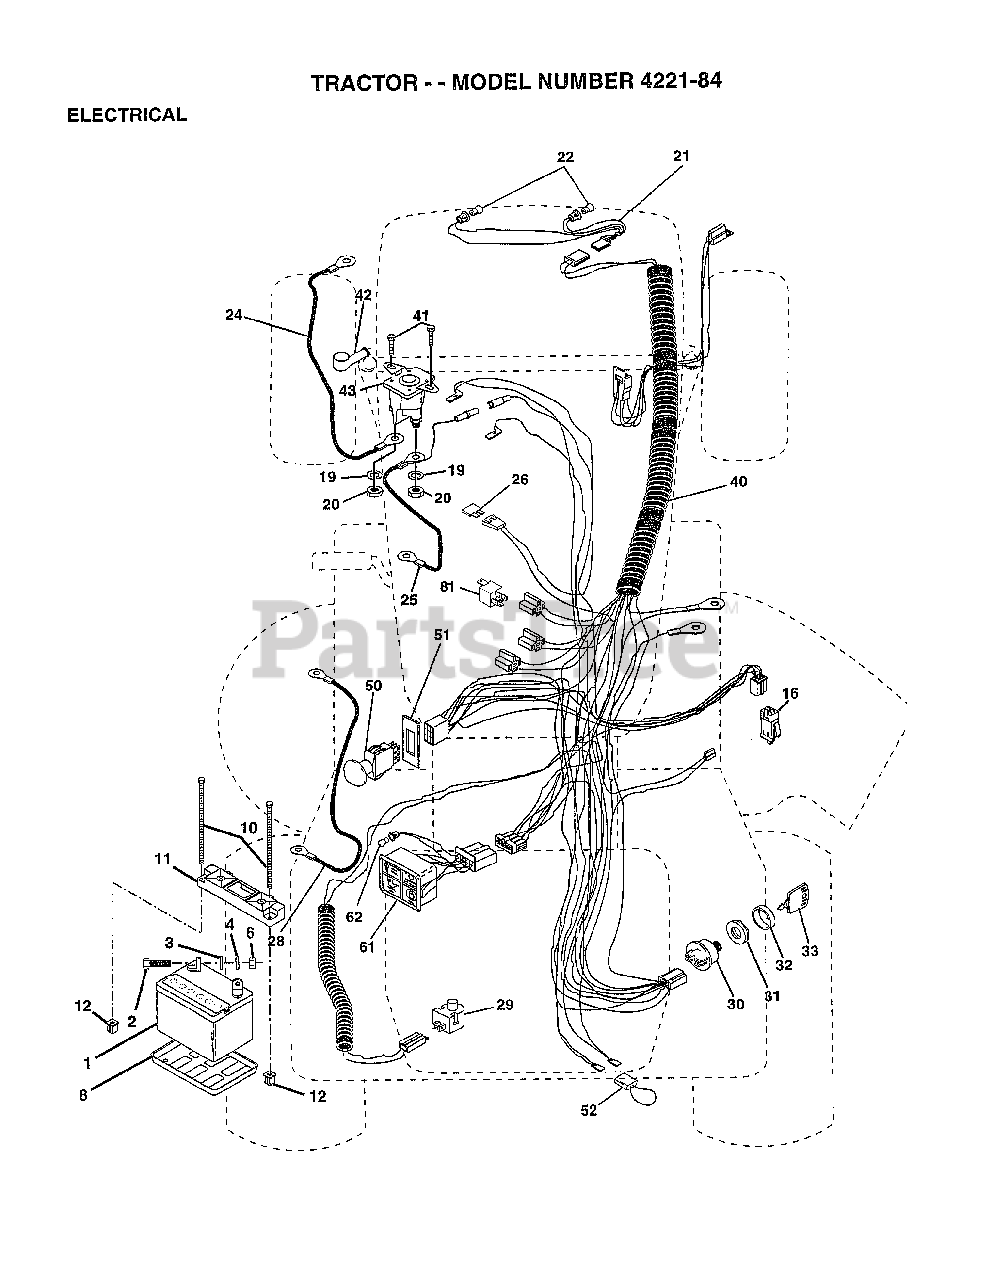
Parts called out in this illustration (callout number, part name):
3	LOCKWASHER
4	WASHER
8	"TRAY T, BATTERY"
11	HOLDDOWN BATTERY
16	SWITCH INTERLOCK
20	NUT
21	"HARNESS,LIGHT SOC"
22	HEADLAMP BULB
24	CABLE.BATY.22.RED
25	CABLE.BATRY.4GA.
26	FUSE HYT
28	"CABLE BATTERY,GRD"
29	SWITCH.PLUNGER
30	SWITCH IGN 4POS
31	NUT IGNITION
32	COVER KEY SWITCH
33	KEY
40	HARNESS.IGNITION
41	SCREW
50	PTO SWITCH.BLK
51	RING RETAIN PTO
52	PROTECTION LOOP
61	LIGHT.PKG.ASM.
62	BULB LIGHT T
81	RELAY ASSY T
